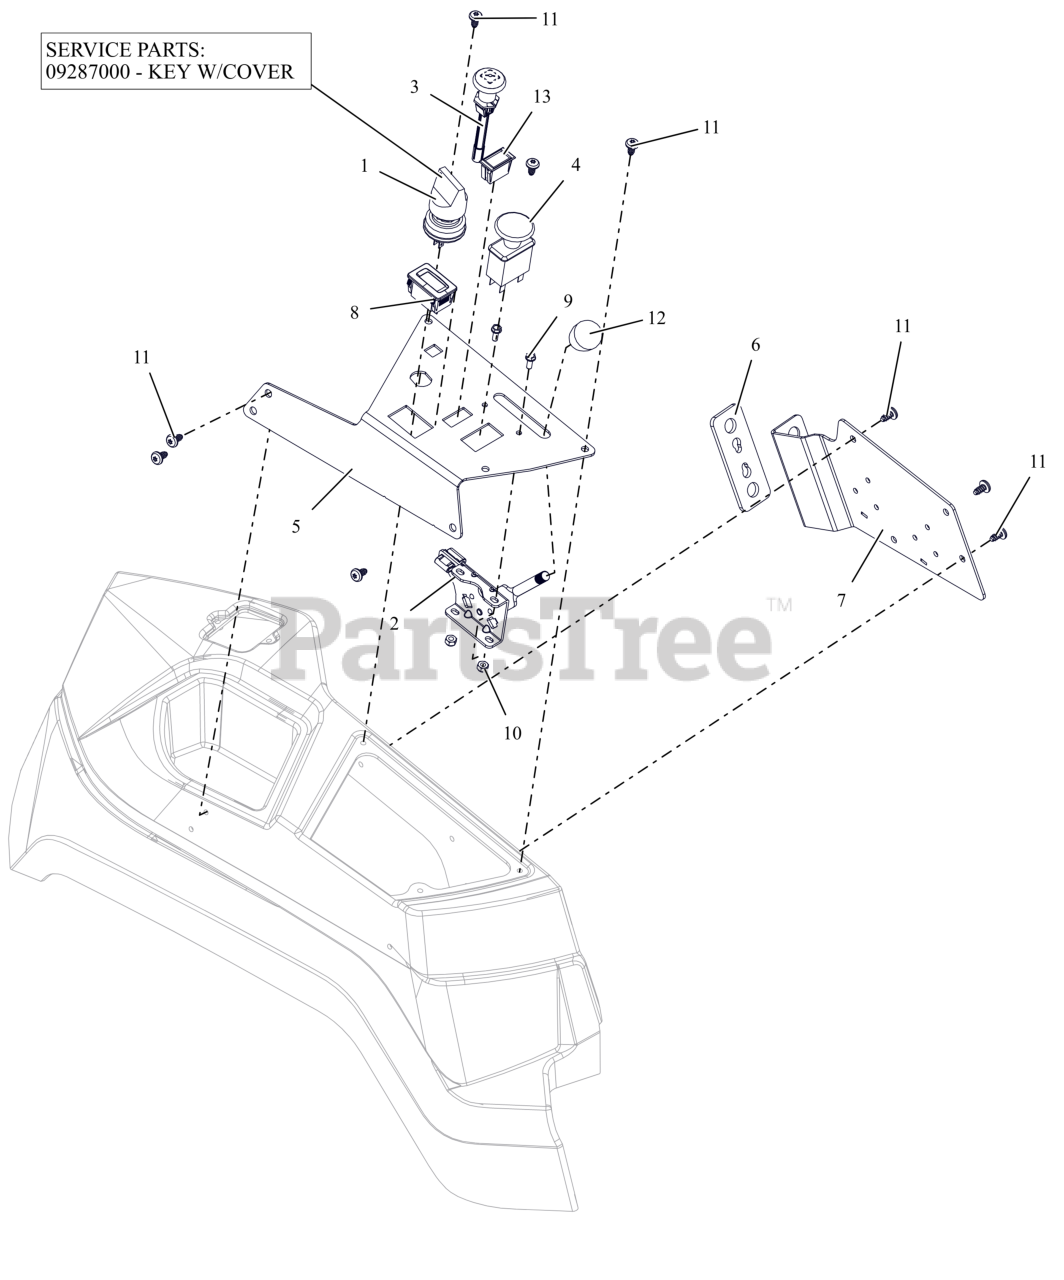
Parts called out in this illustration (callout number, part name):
1	SWITCH, IGNITION
1	KEY, W/ SHIELD
2	CABLE, PRO THROTTLE CONTROL
3	CABLE - CHOKE, SNAP-IN
4	SWITCH, CLUTCH
5	PLATE, APEX CONTROL PANEL
6	PLATE, CONTROL PANEL SPACER
7	BRKT, FENDER/RELAY MOUNTING
8	HOUR METER
9	BLT, HWH #10-24X.50 ZCC
10	NUT-LK-NYL #10-24 G2 ZCC
11	SCR-PAN .25-15X.50 6L H/LZB500
12	KNOB-CONTROL-BLACK .38-16X.50
13	SWITCH,BLANK
